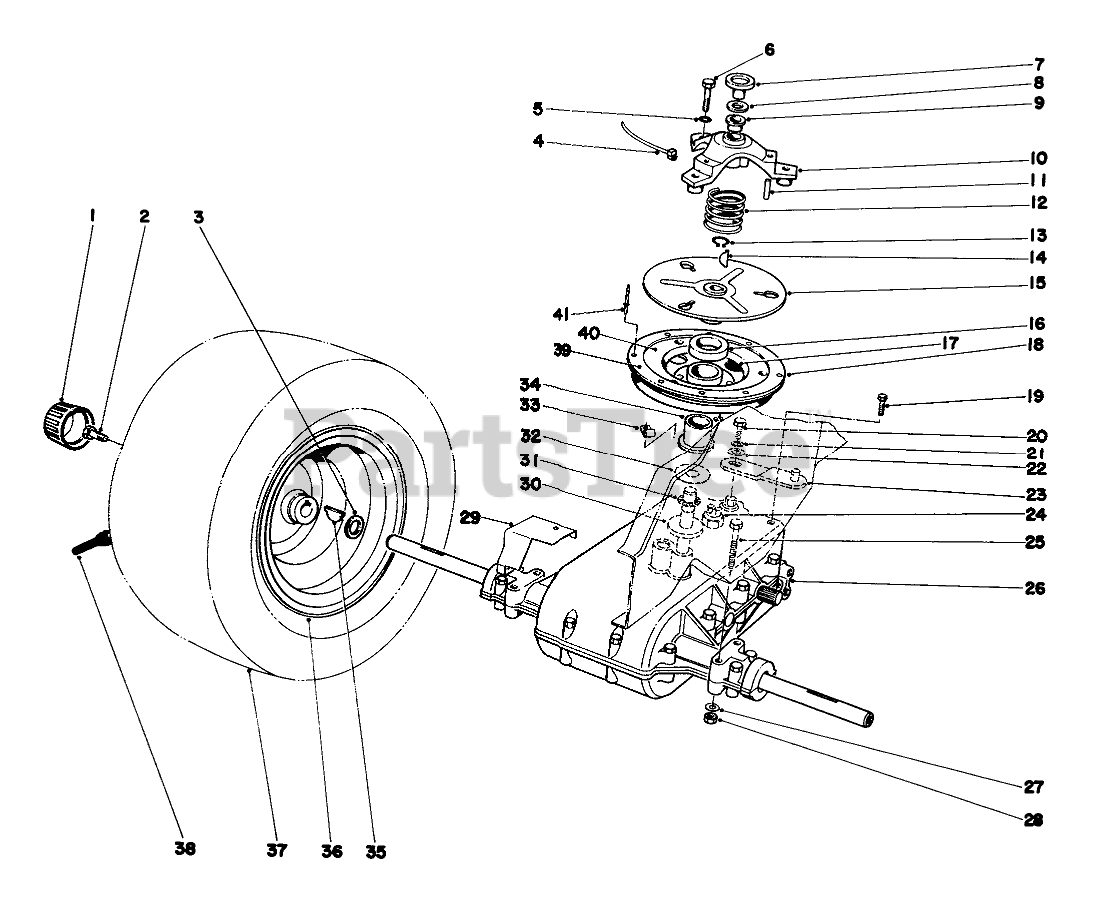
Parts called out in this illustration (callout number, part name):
1	Cap-Hub
2	CAPSCREW 3/8 16 3/4
3	SPACER-WHEEL
4	TIE-MOUNT, PUSH
5	WASHER-LOCK
6	SCREW-HH
7	CLUTCH CAP
8	THRUST RACE
9	BUSHING-FLANGE
10	Cover Clutch (Incl. Ref. #15 & 17)
11	NEEDLE BRG
12	COMPRESSION SPRING
13	RING-SNAP, EXTERNAL
14	KEY-WOODRUFF
15	Clutch Plate
16	WASHER FELT
18	Sheave Assembly (Incl. Ref. #34 & 39-41)
19	SCREW-HWHTF
20	SCREW-HH
21	WASHER-LOCK
22	WASHER-FLAT
23	SHIFT LEVER WA B
24	NEUTRAL SWITCH
25	SCREW-HH
26	Transaxle
27	WASHER-PLAIN
28	NUT-LOCK, CONE
29	GRASS SHIELD B
30	SPACER
31	NEEDLE BRG
32	THRUST WASHER
33	CLIP-FUEL LINE
34	Bushing
36	Rim
38	Tube
39	CLUTCH PAD
40	Retainer Ring
41	Rivet
